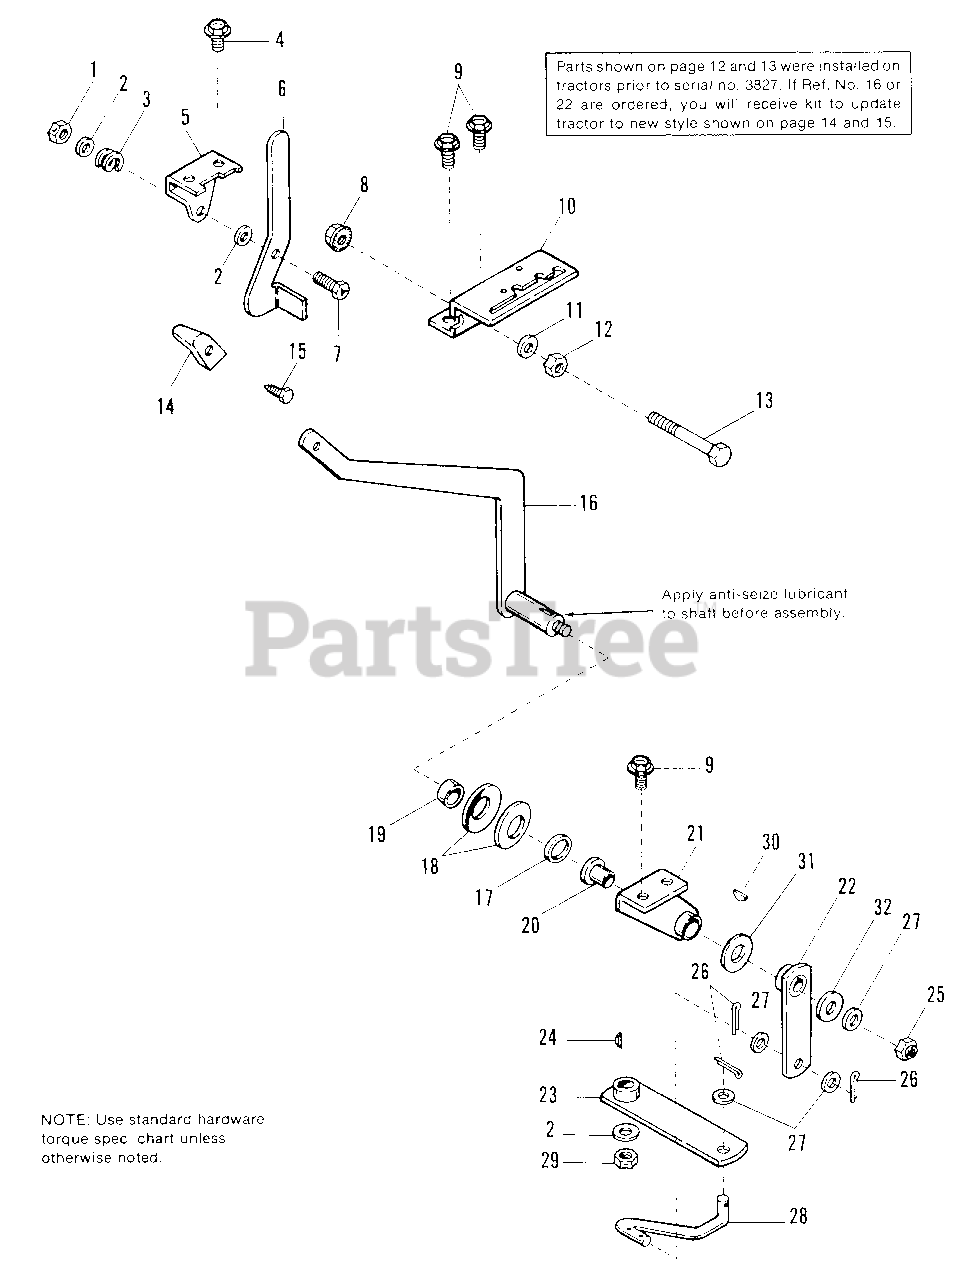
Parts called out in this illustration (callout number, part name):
1	NUT, Hex, Lock, 5/16-18
2	WASHER, Plain, 5/16
3	WASHER, Spring, Double, 3/8
4	SCREW, Taptite, 1/4-20 x 1/2
5	SUPPORT, Handle, Neutral
6	HANDLE, Neutral
7	CAPSCREW, Hex, 5/16-18 x 1-1/4
8	NUT, Hex, Flange Lock, 1/4-20
9	SCREW, Taptite, 5/16-18 x 3/4
11	WASHER, Plain
12	NUT, Hex, 1/4-20
13	CAPSCREW, Hex, 1/4-20 x 2-1/4
15	SCREW, Taptite, 1/4-20 x 1
16	LEVER ASSY., Control
17	WASHER, Special
18	WASHER, Spring
21	SUPPORT ASSY., Control
22	ARM ASSY., Control, Upper
23	ARM ASSY., Control
24	KEY, Woodruff, #3, 1/8 x 1/2
25	NUT, Hex, Lock ESNA
26	PIN, Cotter
27	WASHER, Plain, 13/32 x 1
28	LINK, Control
29	NUT, Hex. Lock, 3/8-16
30	KEY, Woodruff, #3, 1/8 x 1/2
31	WASHER, Thrust, 16 ga. 5/8 x 1
